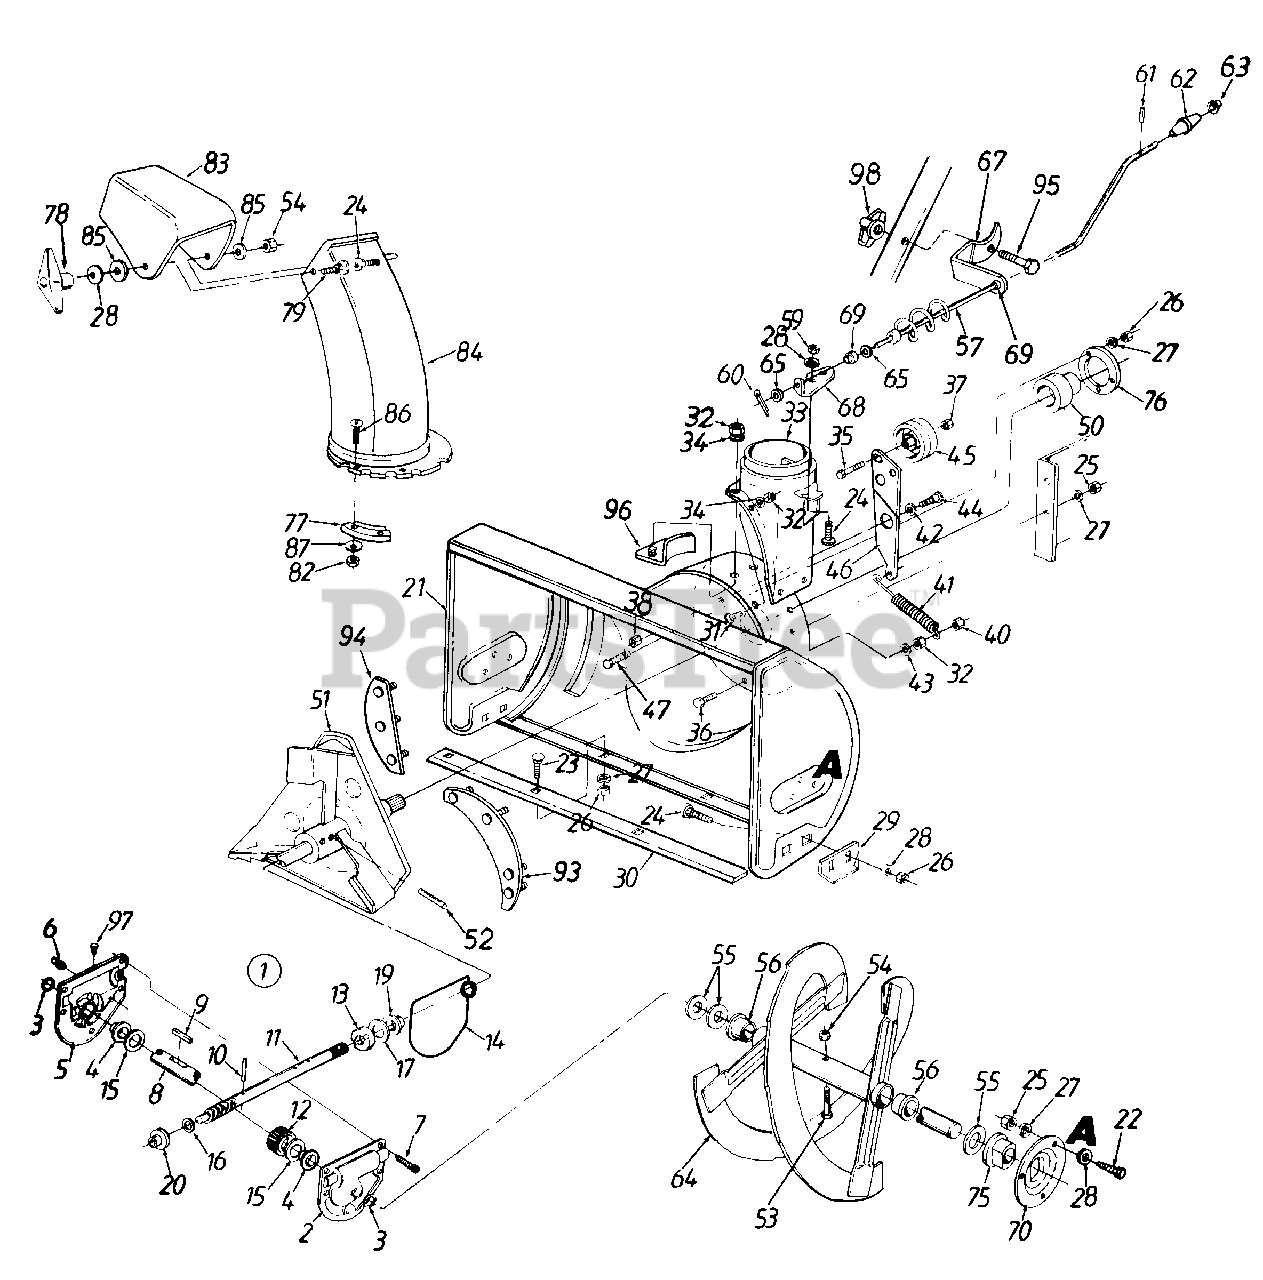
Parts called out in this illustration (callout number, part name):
1	Worm Drive Ass'y. Comp.
2	Reducer Housing - L.H.
3	Oil Seal
4	Flange Bearing .75" I.D.
5	Reducer Housing - R.H.
6	Grease Fltting
7	Hex TT-Tap Scr. 1/4-20 x .75" Lg.
8	24" Auger Shaft
9	#61 Hi-Pro Key 3/16" x 5/8" Dia.
10	Spiral Pin 1.25" Lg.
11	Impeller Shaft
12	Worm Gear
13	Thrust Collar
14	Oil Seal
15	Fl-Wash .76" I.D. x 1.5" O.D.
16	Fl-Wash .5" I.D. x 1" O.D.
17	Fl-Wash .76" I.D. x 1.49" Q.D.
19	Flange Bearing .75" I.D.
20	Flange Bearing .503" I.D.
21	24" Auger Housing Ass'y.
22	Hex Bolt 5/16-24 x .75" Lg.
23	Carriage Bolt 5/16-18 x .62" Lg.
24	Carriage Bolt 5/16-18 x .75" Lg.
25	Hex Nut 5/16-24 Thd.
26	Hex Nut 5/16-18 Thd.
27	L-Wash. 5/16" I.D.
28	Bell-Wash .345" I.D. x .88" O.D.
30	24" Shave Plate
31	Truss Mach. Scr. 1/4-20 x .5" Lg.
32	Hex Nut 1/4-20 Thd.
33	Chute Adapter
34	Spring Washer 1/4" I.D.
35	Hex Bolt 3/8-24 x 1.5" Lg. (Gr. 5)
36	Hex Bolt 1/4-20 x .75" Lg. (Gr. 5)
37	Hex Ins. L-Nut 3/8-24 Thd.
38	Hex Top L-Nut 3/8-16 Thd.
40	Hex L-Nut 1/4-20 Thd.
41	Ext. Spring 3.6" Lg.
42	Fl-Wash. 5/8" I.D. x 1.25"
43	L-Wash. 1/4" I.D.
44	Shld. Bolt .625" Dia. x .170" Lg.
45	Fl-Idler 2 75" O.D.
47	Hex Bolt 5/16-18 x 5/8" Lg.
50	Ball Bearing .75" I D.
52	Spiral Pin 1.5" Lg
53	Shear Bolt 5/16-18 x 1.5" Lg
54	Hex Cent. L-Nut 5/16-18 Thd.
55	Fl-Wash .76" I.D. x 1 49"
56	Flange Bushing 8" I.D.
57	Chute Crank Ass'y.
59	Hex Ins. L-Nut 5/16-18 Thd.
60	Cotter Pin 3/32" Dia. x .75"
61	Roll Pin 1/8" Dia. x .63" Lg.
62	Chute Crank Knob
63	Push Nut
65	Fl-Wash .385" I D. x .62" O.D.
69	Plastic Bushing 38" I.D.
75	Plastic Bearing w/Flats
76	Bearing Housing
77	Chute Flange Keeper
78	Knob
79	Carriage Bolt 5/16-18 x 1.5" Lg.
82	Hex L-Nut 1/4-20 Thd.
83	Upper Chute
84	Lower Chute
85	Fl-Wash .344" I D. x 1.125"
86	Truss Mach. Scr. 1/4-20 x .75" Lg.
87	Fl-Wash. 1/4" I D.
96	Chute Reinforcement
98	Hand Knob
